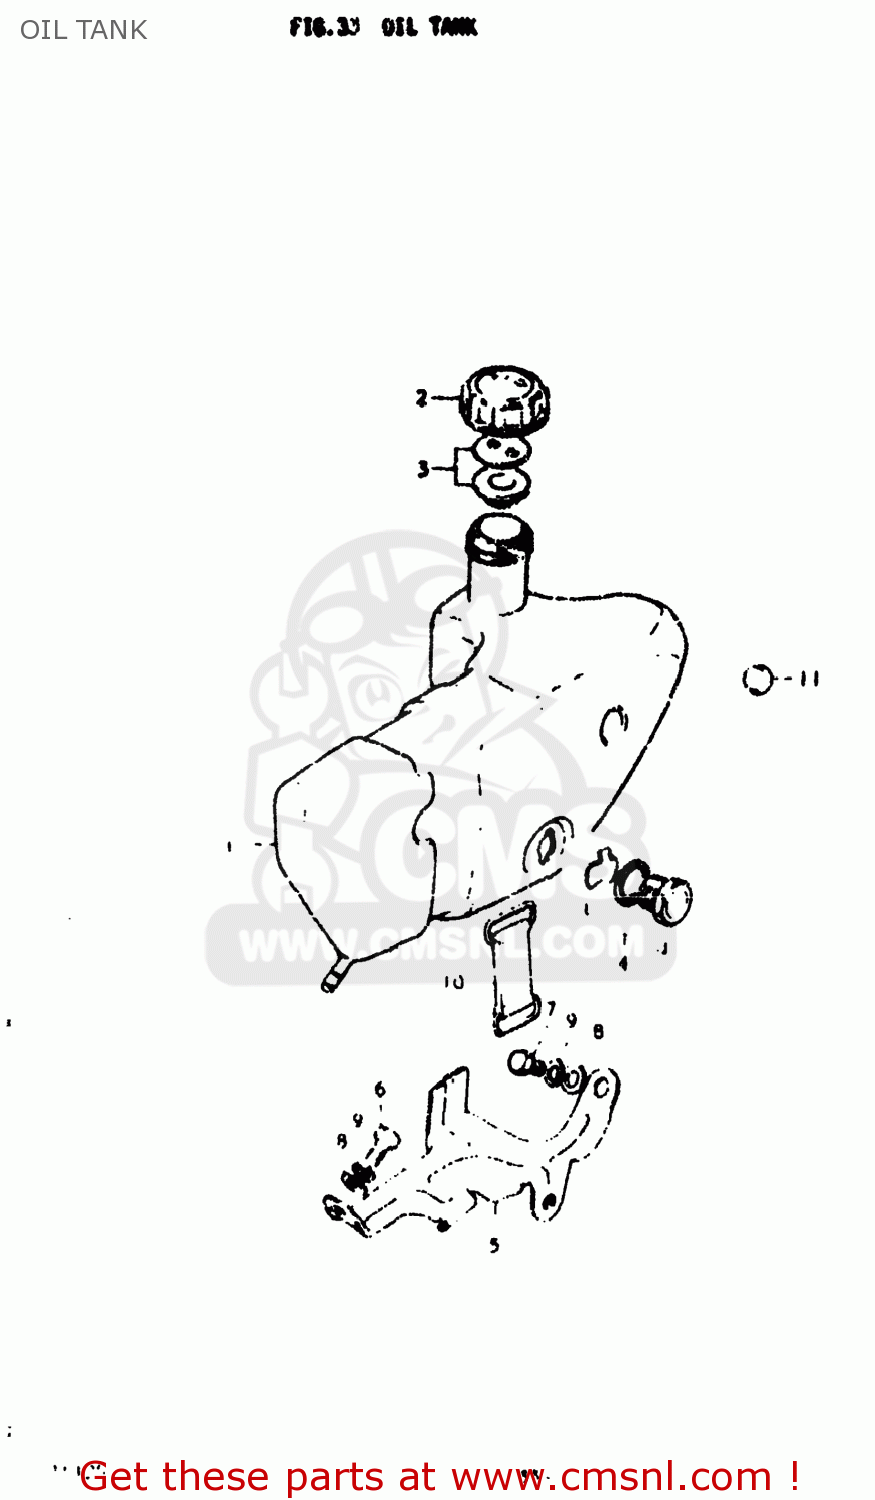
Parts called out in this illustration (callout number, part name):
1	TANK,OIL
2	CAP,OIL TANK
3	LENS,OIL LEVEL INSPECTION
4	LENS,OIL LEVEL INSPECTION
6	BOLT
7	BOLT
8	WASHER
9	LOCK WASHER
10	BAND
11	CUSHION
